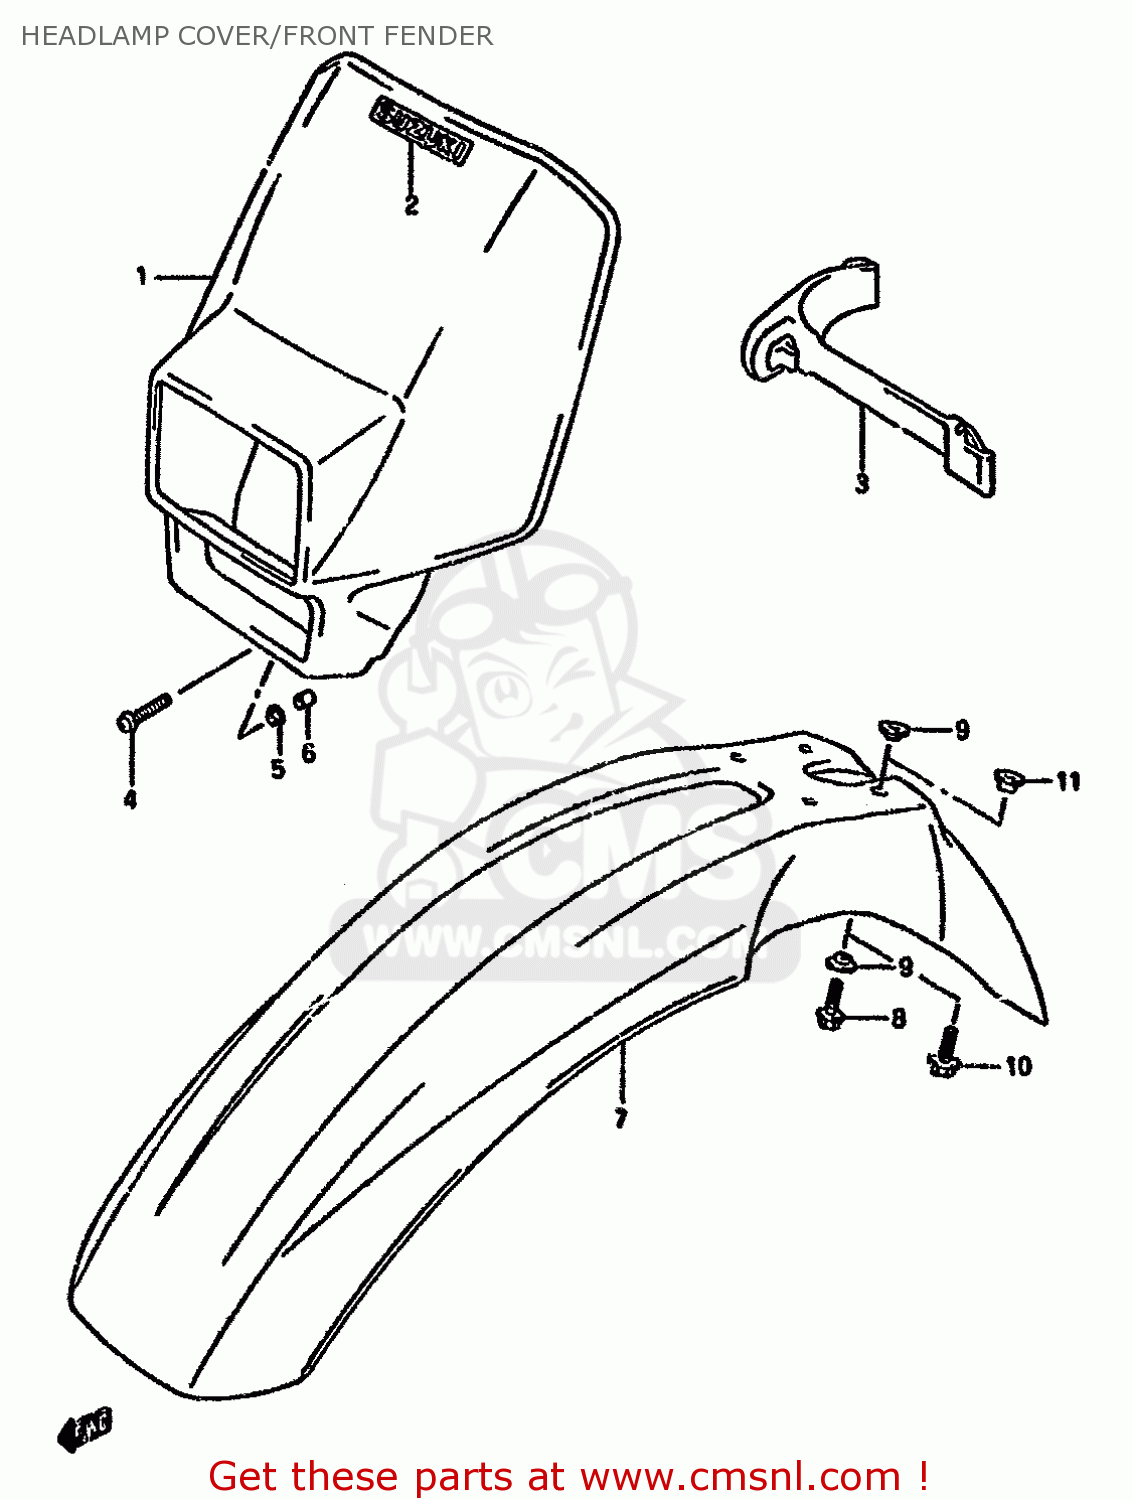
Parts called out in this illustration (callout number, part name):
1	COVER,HEADLAMP
2	EMBLEM,HEADLAMP COVER
3	BAND,HEADLAMP COVER
4	SCREW
5	WASHER
6	SPACER(6.2X12X16)
7	FENDER,FRONT
8	BOLT 6X16
9	WASHER
10	BOLT(6X16)
11	WASHER
